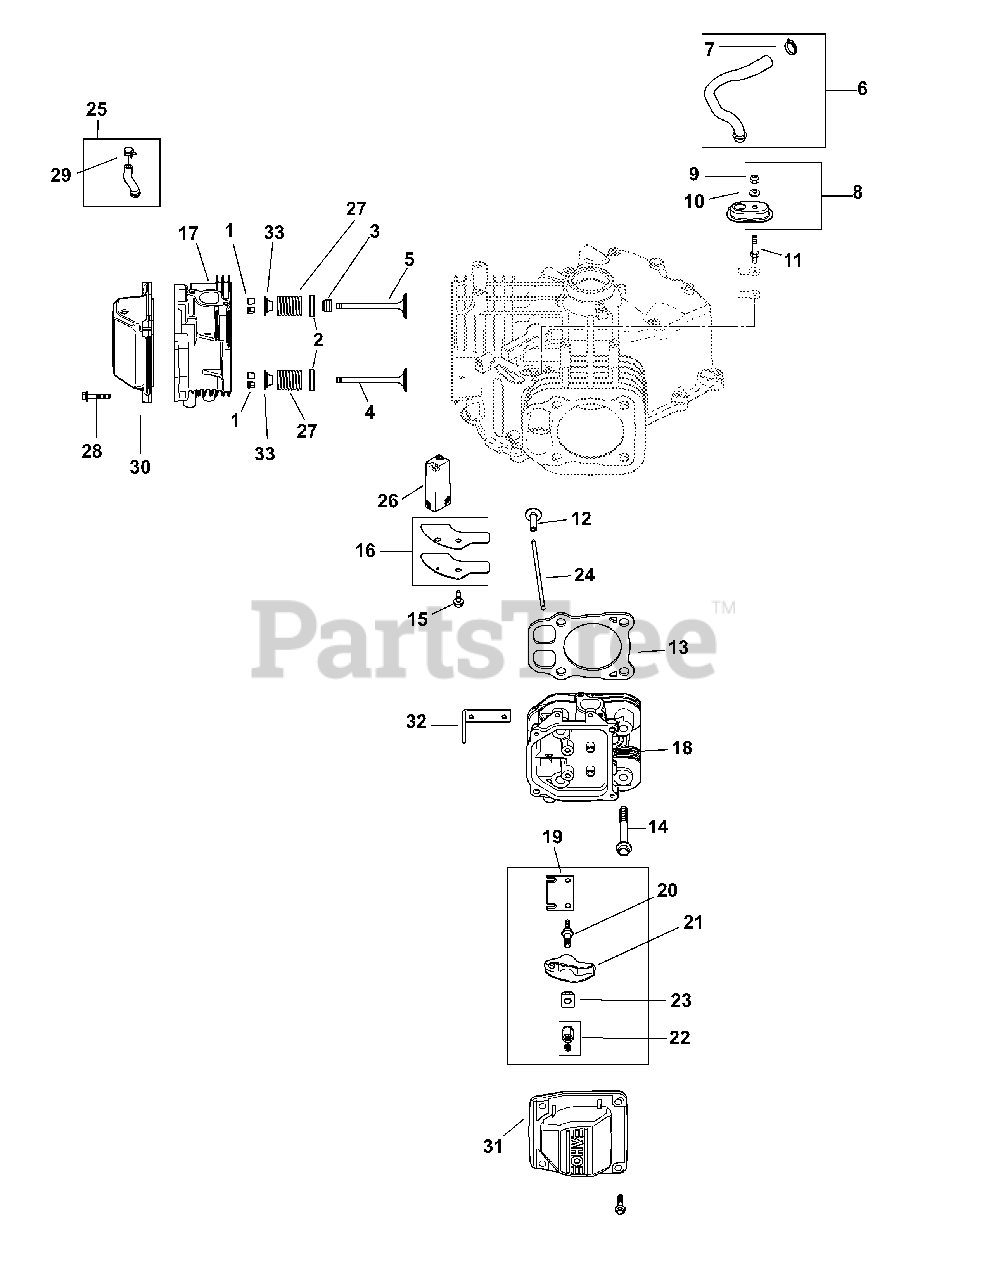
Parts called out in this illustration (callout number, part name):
1	Retainer Kit
2	Spring Retainer
3	Valve Stem Seal
4	Exhaust Valve (STD)
5	Intake Valve (STD)
6	Breather Hose Kit (Inc. #7)
7	Hose Clamp, 1/2
8	Housing Breather Kit (Inc. #9 & 10)
9	Lock Nut, M5 x 8
10	Sealing Washer
11	Breather Cover Stud
13	Cylinder Head Gasket Kit
14	Flange Screw, M10 x 1.5 x 90
15	Flange Screw, M6 x 1.0 x 16
16	Breather Cover
17	Cylinder Head Assembly Kit, #1
18	Cylinder Head Assembly Kit, #2
22	Hex Nut Assembly (Inc. #32)
23	Rocker Arm Pivot
25	Fuel Pump Hose Kit (Inc. #29)
26	Breather Filter
27	Valve Spring
28	Pan Head Screw
30	Rocker Cover
32	Lifting Strap
33	Valve Spring Cap
